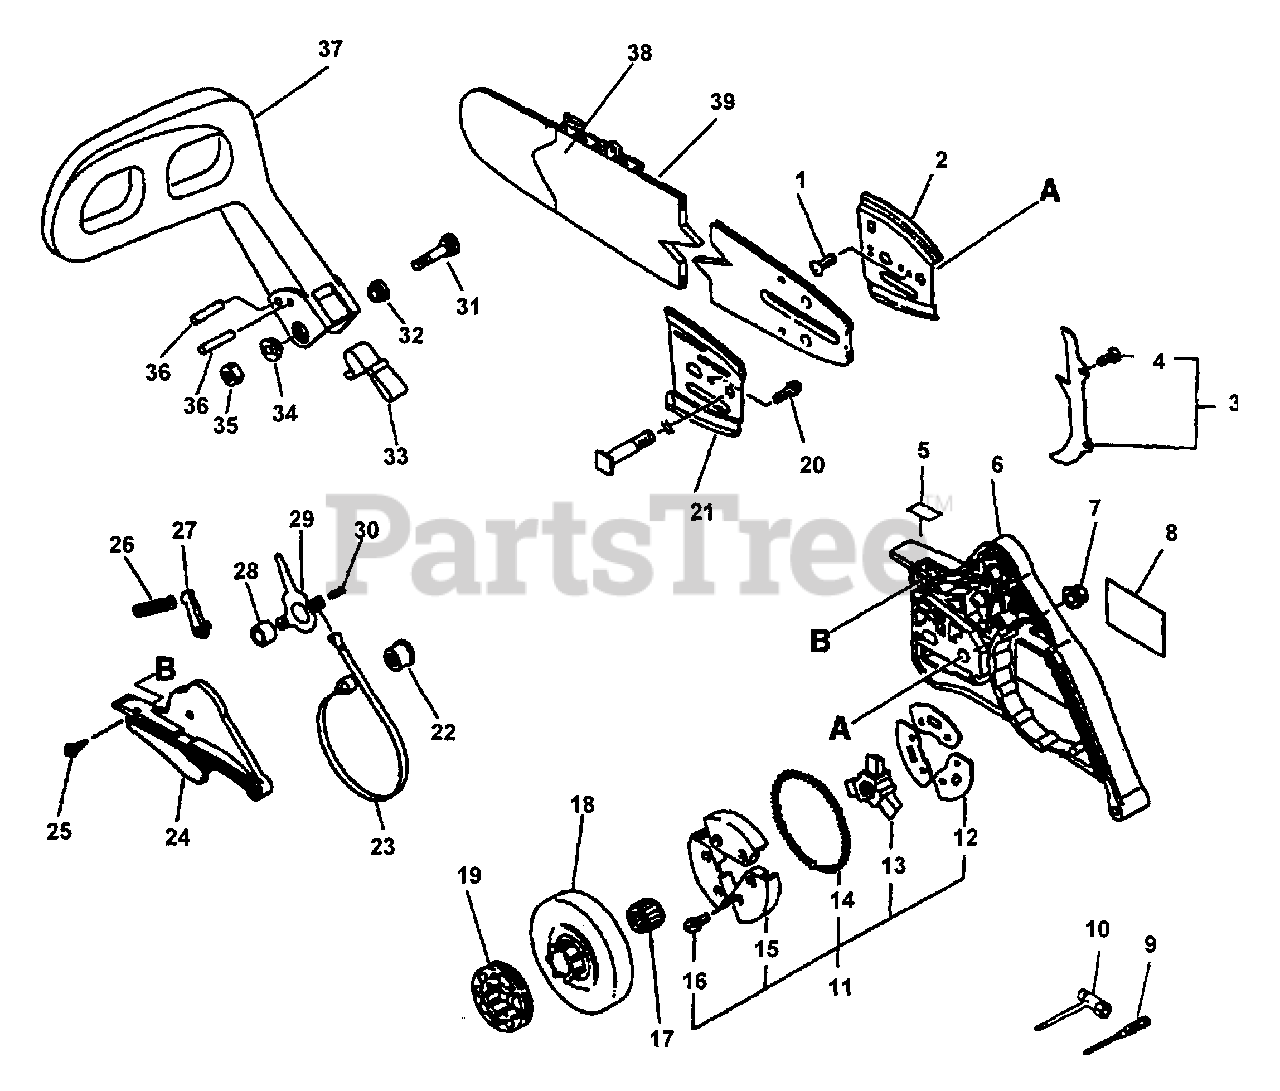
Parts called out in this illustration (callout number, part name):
1	SCREW 4×8
2	PLATE, GUIDE
3	SPIKE KIT, BUMPER
5	LABEL, CAUTION
6	GUARD, SPROCKET
7	NUT, FLANGE M8×1.25
8	LABEL, ECHO
9	SCREWDRIVER, PHILLIPS
10	T-WRENCH 13×19×180
11	CLUTCH ASSY
12	PLATE, CLUTCH
13	HUB, CLUTCH
14	SPRING, CLUTCH
15	SHOE SET, CLUTCH (3PCS)
16	BOLT 4×6
17	BEARING, NEEDLE
18	DRUM, CLUTCH
19	SPROCKET, 0.325 RIM
20	SCREW 3×6
21	PLATE, GUIDE
22	ADJUSTER, BRAKE
23	BAND, BRAKE
24	COVER, BRAKE
25	SCREW 4×10
26	SPRING, COMPRESSION
27	STOPPER, BRAKE
28	SPACER 8×12×9
29	LEVER, BRAKE
30	PIN, SPRING 4×8.8
31	SCREW 5×35
32	COLLAR 5
33	SPRING, RETURN
34	COLLAR 5.3×10×13×L5
35	NUT, LOCK M5
36	PIN 3.5×26
37	LEVER, BRAKE
38	SAWING CHAIN - 16" -- PRO GUARD
38	SAWING CHAIN - 18" -- PRO GUARD
38	SAWING CHAIN - 20" -- PRO GUARD
39	GUIDE BAR - 16" -- DOUBLE GUARD
39	GUIDE BAR - 18" -- DOUBLE GUARD
39	GUIDE BAR - 20" -- DOUBLE GUARD
